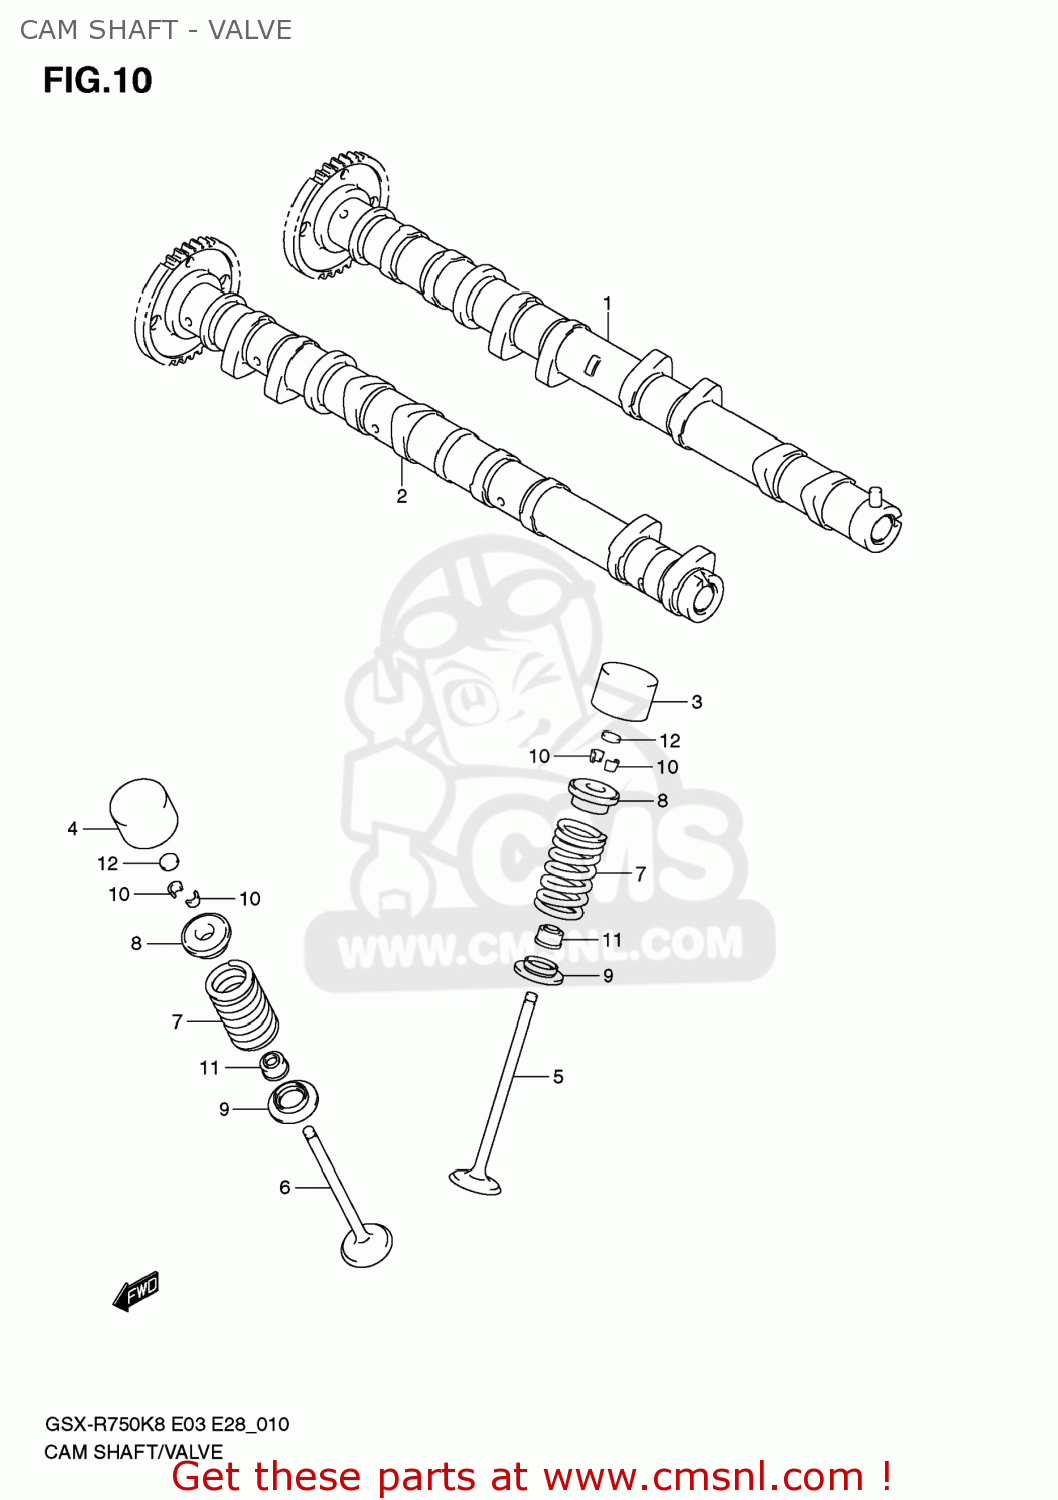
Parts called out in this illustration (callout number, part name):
1	CAMSHAFT,INTAKE
2	CAMSHAFT,EXHAUST
3	TAPPET
4	TAPPET,EXHAUST
5	VALVE,INTAKE
6	VALVE,EXHAUST
7	SPRING,VALVE
8	RETAINER,VALVE SPRING
9	SEAT,VALVE SPRING
10	COTTER VALVE
11	SEAL,OIL(4.5X10X8)
12	SHIM,TAPPET
13	SHIM SET,TAPPET
14	CASE,TAPPET SHIM
